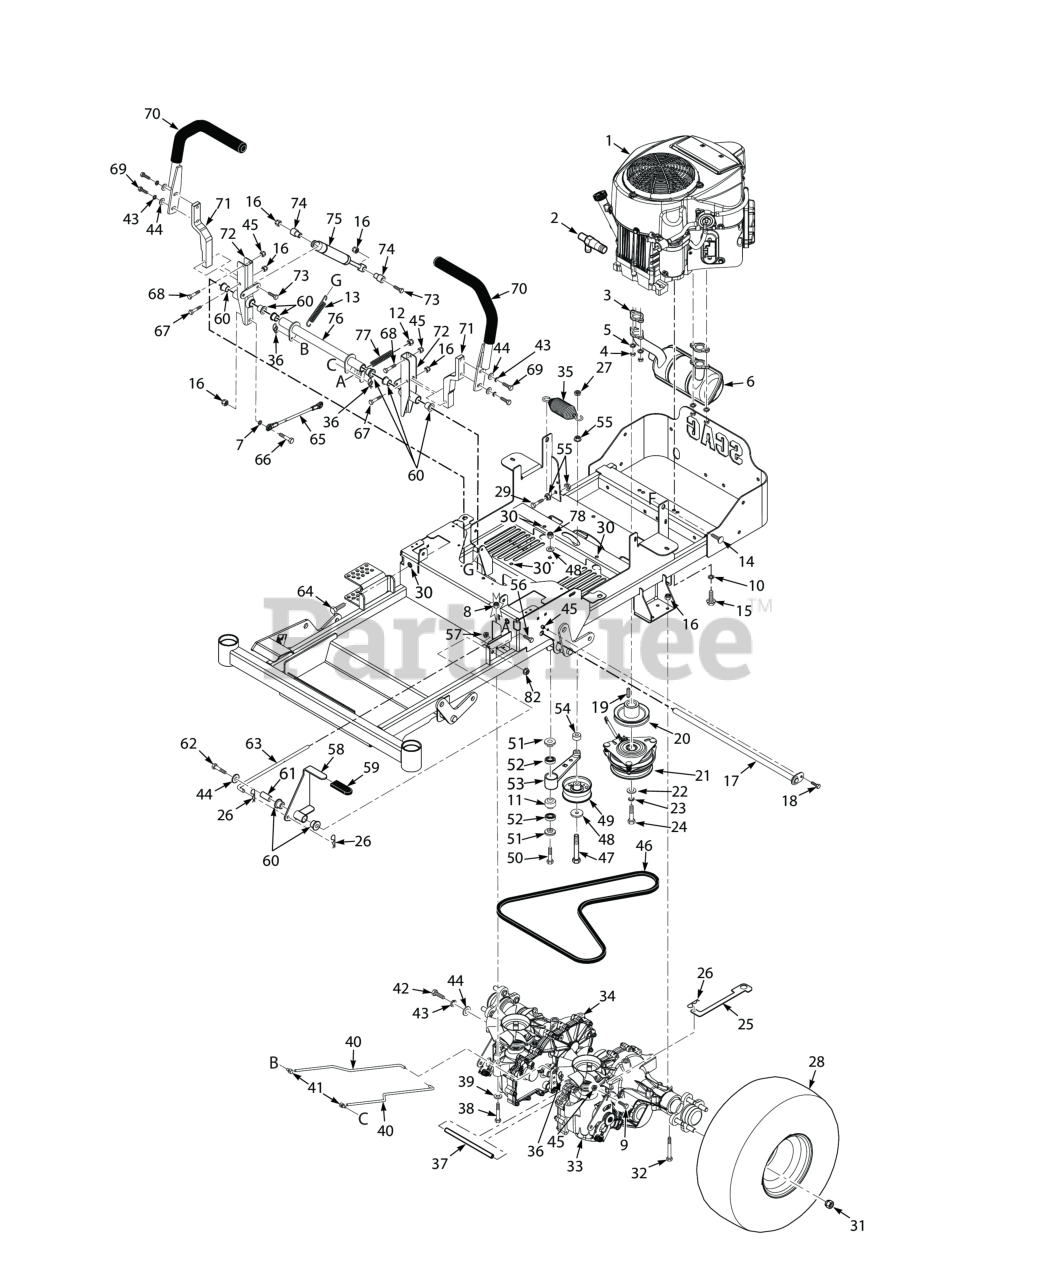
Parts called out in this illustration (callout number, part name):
1	Engine, Kawasaki - FR600V
2	Oil Drain, Kawasaki
3	Gasket, Exhaust
4	Nut, M8 x 1.25 Hex Special
5	Lockwasher, M8 Spring (Kawasaki)
6	Muffler, Kawasaki FR/FS600V
7	Lockwasher, 5/16 (.317 x .586 x .078) Helical Spring
8	Nut, Flange Head Elastic Stop 5/16-18
9	Bolt, Hex Head, 1/4-20 x 1-1/2"
10	Lockwasher, 3/8" Spring, Kawasaki FX / FS
11	Spacer, Bearing
12	Nut, Flange Elastic Stop Nut, 3/8-16
13	Spring, Deck Latch
14	Serr. Fl. Hex Head CPSCR, 1/4-20 x 3/4"
15	Bolt, Hex Head 3/8-16 x 1-1/4", Kawasaki FX / FS
16	HEX NUT, ELASTIC STOP LOCK, 5/16-18
17	Shaft Weldment, Control Arm
18	BOLT, HEX HEAD, 1/4-20 X 5/8
19	Key, 1/4 x 1/4 x 1.25" Pulley Mtg.
20	Pulley, 4-1/2" - 1" Bore
21	Electric Clutch Assembly
22	Flatwasher, 7/16-.469 x 1.75 x .25 (48, 52)
23	Lockwasher, 7/16� Spring
24	Bolt, Hex Head 7/16-20 x 3¼" w/Patch
25	Lever, Dump Valve
26	HAIR PIN, .08 DIAMETER X 1-3/16"
27	Bolt, Hex Head 3/8-16 x 1" Ser. Flg.
28	WHEEL ASSY, 20 X 10-10
29	Bolt, Hex Head 3/8-16 x 1-1/2" Grade 8 Black
30	Threaded insert, Hex Head (Pressed)
31	Wheel Nut, 1/2-20 x 13/16
32	Bolt, Hex Head, 5/16-18 x 2.75 Zinc.
33	Transaxle, LH- ZT-2800
34	Transaxle, RH- ZT2800
35	Spring, Transmission Drive
36	Pin, Rue Cotter 3/8" Diameter
37	Spacer, Axle
38	BOLT, HEX HEAD, 5/16-18 X 2-1/4
39	Flatwasher, 5/16-.375 x .875 x .083 (35BV & 37BV-EFI)
40	Rod, Brake
41	Joint, Swivel
42	Bolt, Hex Head 3/8-16 x 2-1/4" - 61"
43	Lockwasher, 3/8" Spring, Kawasaki FX / FS
44	Flatwasher, 3/8" Special (.391 x .938 x .105)
45	HEX, NUT, ELASTIC STOP LOCK, 1/4-20
46	Belt, Transmission SZL-36
47	Capscrew, Hex Head 3/8-16 x 3-3/4"
48	Flatwasher, 3/8 (.391 x .938 x .105 HD) Grade 8
49	Pulley, 3-1/2" Dia.
50	Bolt, Hex Head 3/8-16 x 3" - 52"
51	Spacer, Controls
52	BEARINGS, BALL, NEUTRAL RETURN
53	Trans. Idler Arm Assy. (Includes 24, 79)
54	Spacer, Idler Pulley - SFZ61
55	NUT, 3/8-16 SERRATED FLANGE HEX HEAD
56	Bolt, Hex Head 5/16-18 x 1-1/2" (Right Front Engine Mounting, Briggs and Kohler Only)
57	Nut, Flange Elastic Stop Nut, 3/8-16
58	Brake Lever Assembly (INCL 59,60)
59	Grip, Brake Handle
60	Bearing
61	Pivot, Brake Lever
62	Capscrew, Hex Head 3/8-16 x 2-1/2"
63	Rod, Upper Brake Linkage
64	Bolt, Hex Head 3/8-16 x 3.0
65	Linkage Assembly, Steering
66	Bolt, 5/16 - 18 x 1 - 1/4" Hex Head
67	Bolt, Hex Head 5/16-18 x 1-1/2" - Front
68	Bolt, Hex Head, 1/4-20 x 1-1/4"
69	Bolt, Hex Head, 3/8-16 x 1 Gr. 5
70	Handlebar W/ Grip, SZL-36
71	Lever, Control Arm
72	Control Arm Weldment, SZL-36
73	Bolt, Hex Head 5/16-18 x 2-1/2" (x3) (35BV & 37BV-EFI)
74	Spacer, Pump Dampener
75	Damper, Steering
76	Bellcrank Assembly, Brake
77	Spring, Brake
78	HEX NUT, ELASTIC STOP LOCK, 3/8-16
